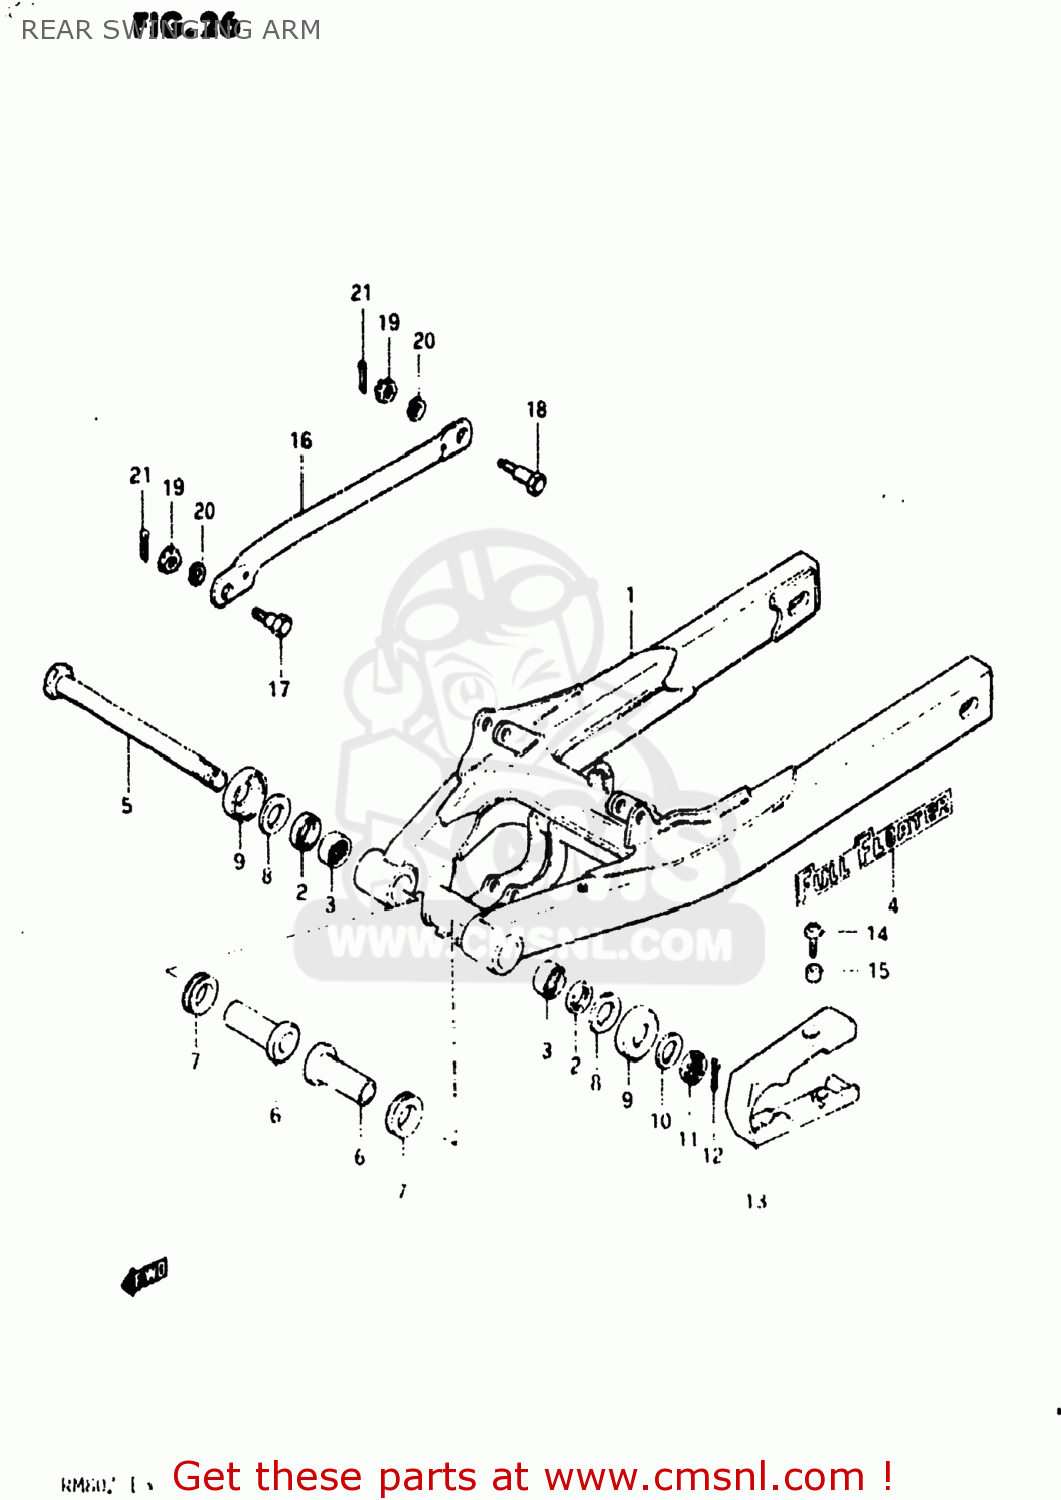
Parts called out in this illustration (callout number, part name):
1	SWING ARM ASSEMBLY,REAR
2	SEAL,OIL(17X24X3)
3	ROLLER BEARING (17X24X2
4	EMBLEM
5	SHAFT,REAR SWING ARM
6	SPACER,RR SWGARM PIVOT
7	SEAL,OIL(17X24X5)
8	WASHER
9	COVER,RR SWGARM DUST SEAL
10	WASHER
11	NUT, REAR AXLE
12	COTTER PIN
13	BUFFER,CHAIN TOUCH DEFLECTOR
14	SCREW,CHAIN TOUCH DEFEND
15	SPACER (5.5X8X4)
16	LINK,REAR TORQUE
17	BOLT(8X22)
18	BOLT(8X21)
19	NUT
20	LOCK WASHER
21	PIN 20X20
